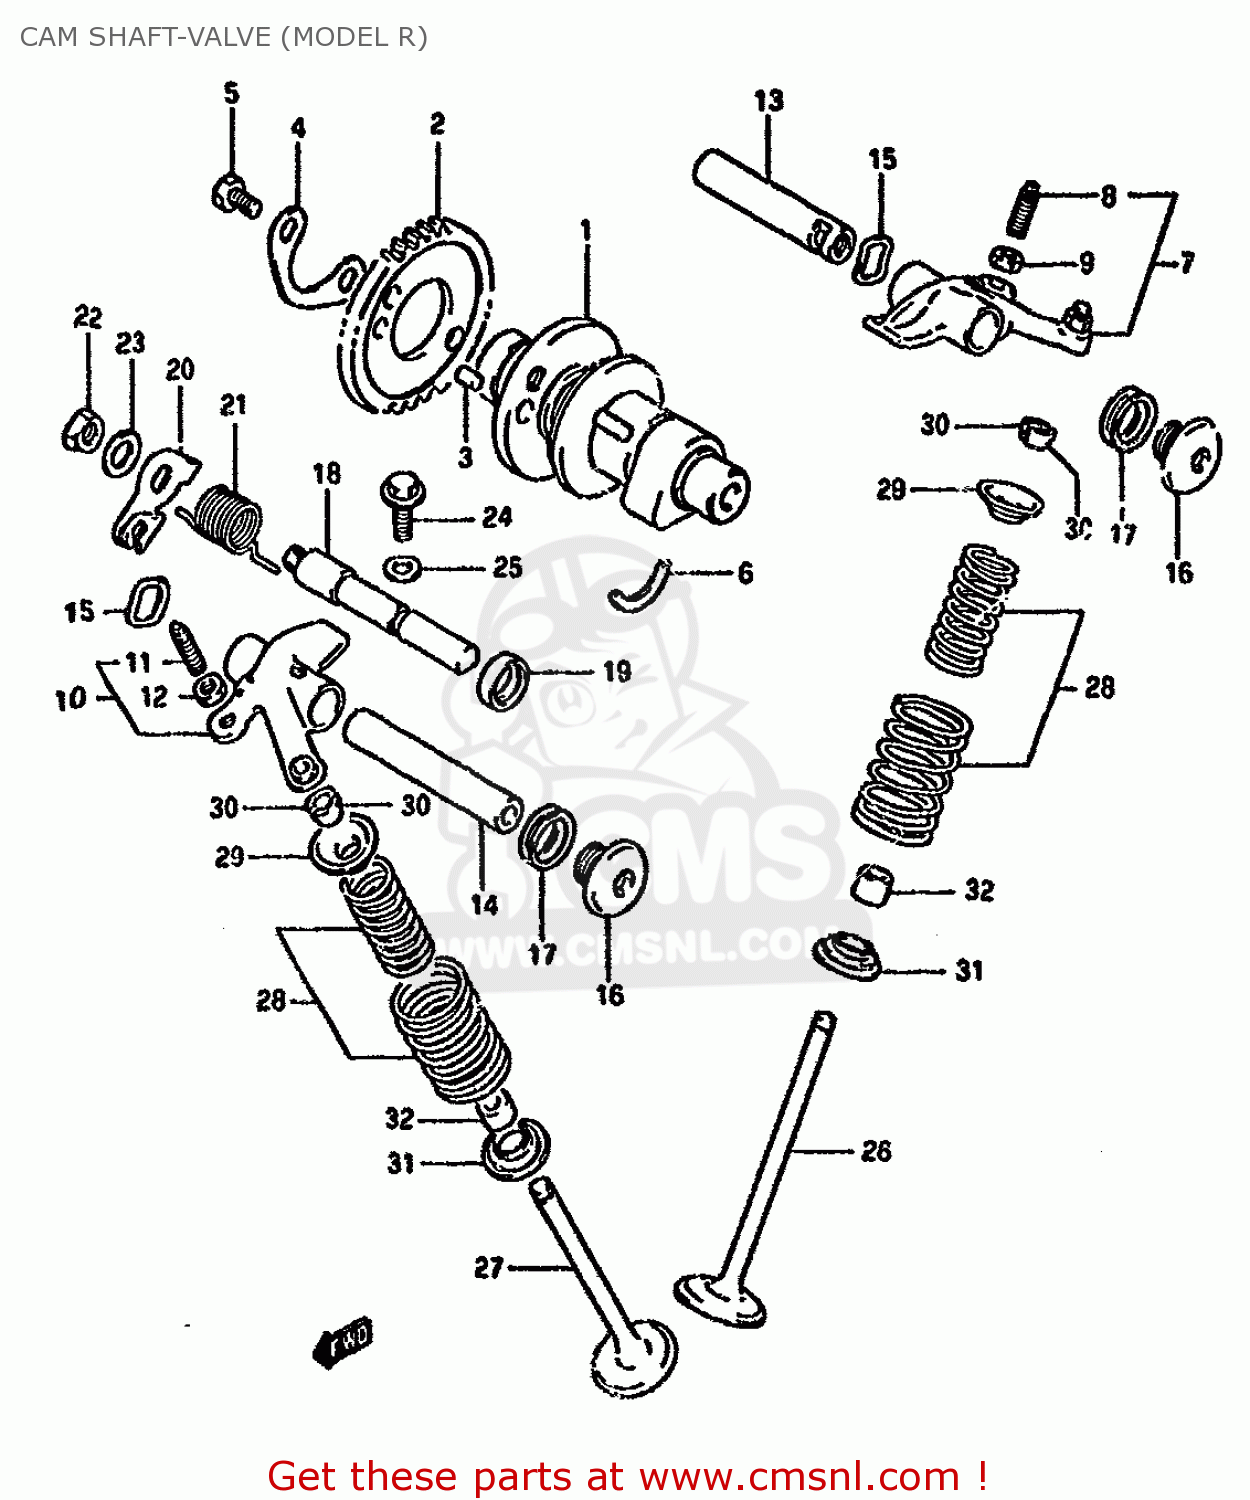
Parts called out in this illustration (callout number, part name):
1	SHAFT COMP,CAM
2	SPROCKET,CAMSHAFT
3	PIN(5X8)
4	WASHER,SPROCKET
5	BOLT(6X10.5)
6	C RING
7	ARM,VALVE ROCKER,INTAKE
8	SCREW,TAPPET ADJUSTING
9	NUT,TAPPET ADJUSTING
10	ARM,VALVE ROCKER EXHAUST
11	SCREW,TAPPET ADJUSTING
12	NUT,TAPPET ADJUSTING
13	SHAFT,VALVE ROCKER ARM INTAKE
14	SHAFT,VALVE ROCKER ARM EXHAUST
15	WASHER
16	PLUG,14X12
17	GASKET(13.8X18.8X4.8) (NAS)
18	SHAFT,DECOMP
19	SEAL,OIL(10X17X6)
20	LEVER,DECOMPRESSION SHAFT
21	SPRING
22	NUT
23	WASHER
24	BOLT
25	GASKET(6.4X11.5X0.8) (NAS)
26	VALVE,INTAKE
27	VALVE,EXHAUST
28	SPRING SET,VALVE
29	RETAINER,VALVE SPRING
30	COTTER VALVE
31	SEAT,VALVE SPRING
32	SEAL,OIL(5X10X9.7)
